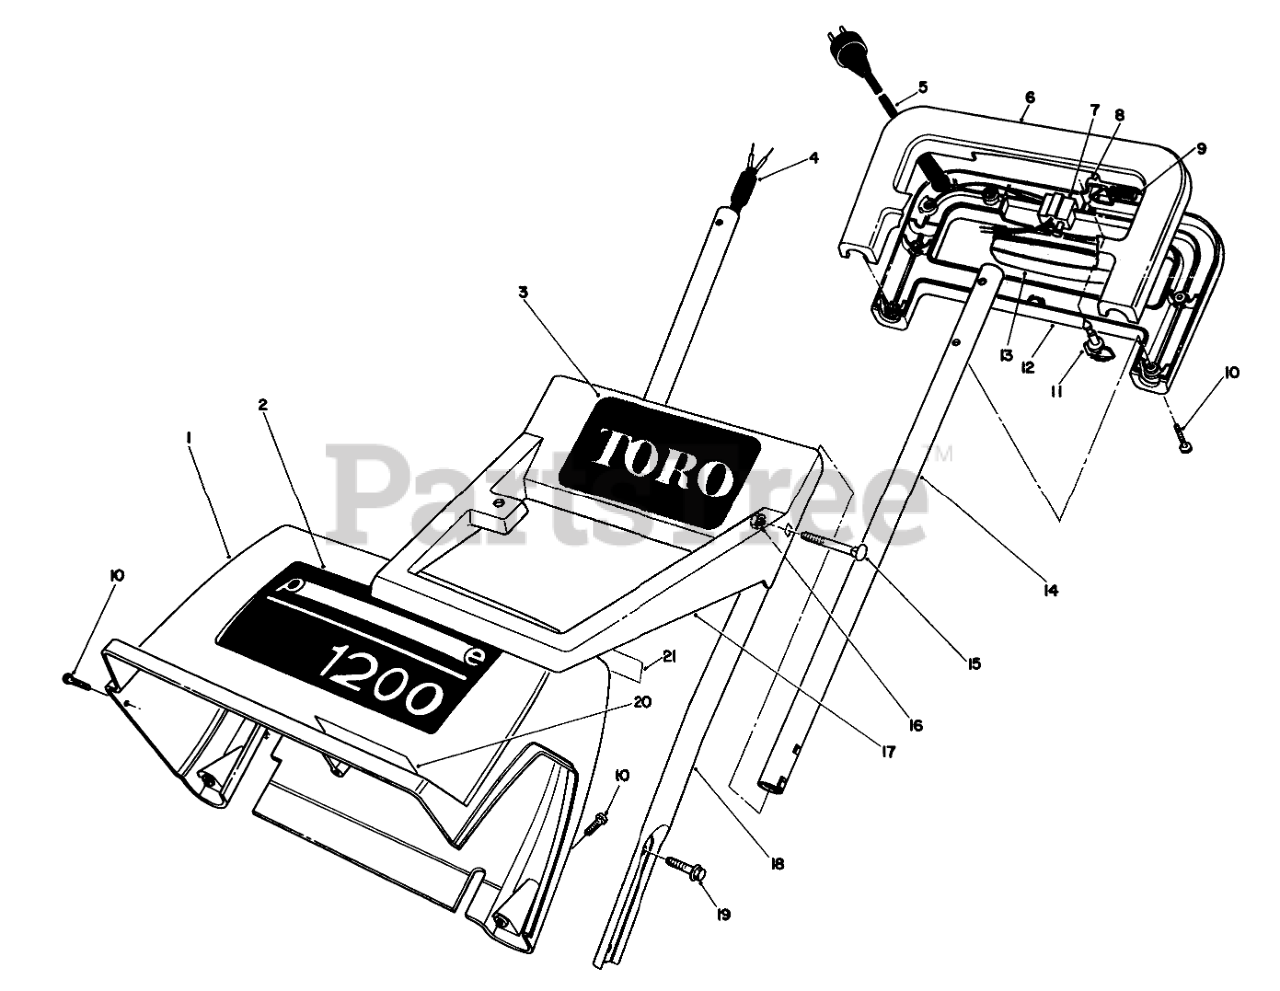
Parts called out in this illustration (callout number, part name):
1	Shroud (Incl. Ref. #2, 20, & 21)
2	DECAL-TORO 1200
3	DECAL-TORO
4	WIRE HARNESS
5	SUPPLY CORD, 1200
6	1200PC-CONTROL HANDLE U
7	SWITCH-STARTER
8	LOCKOUT, 1200
9	COMP SPRING
10	Screw
12	1200 P CONTROL HANDLE L
13	SWITCH BAR, 1200 PC
14	UPPER TUBE, S-120
15	Bolt-Carriage
16	NUT-LOCK, NI
17	MIDDLE HANDLE, 1200
18	LOWER TUBE, LH, S-120
19	Screw
20	Decal-Danger
21	Decal-U.L.
